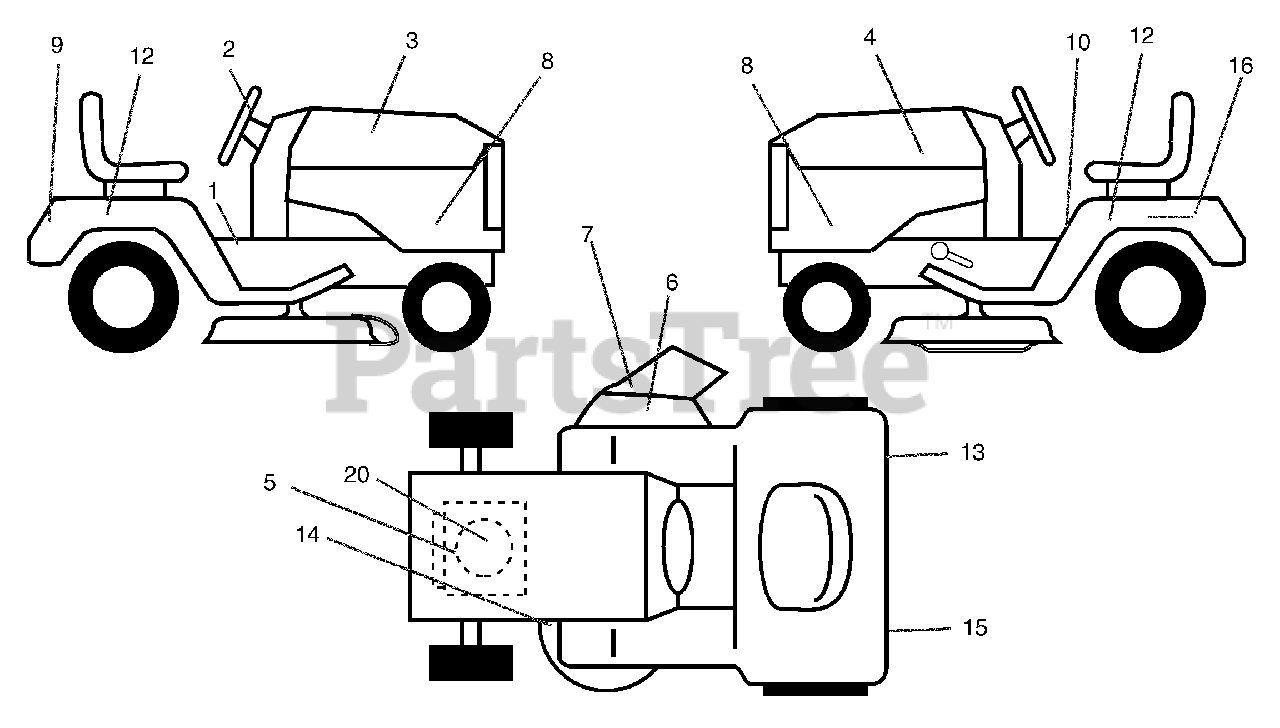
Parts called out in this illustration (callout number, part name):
1	Decal Instruction Operat English/French
2	Decal Ins Strg Wh
3	Decal Hood Rh
4	Decal Hood Lh
5	Decal Replacement
6	Decal, Warning
7	Decal Deck "B" 42"
8	Decal Hood Side Panel
9	Decal Fender Logo
10	Decal Danger English
12	Decal Fender
13	Decal Reflector LH
14	Decal V-belt Schematic 42"
15	Decal Reflector RH
16	Decal Battery Danger/Poison
20	Decal HP Engine
